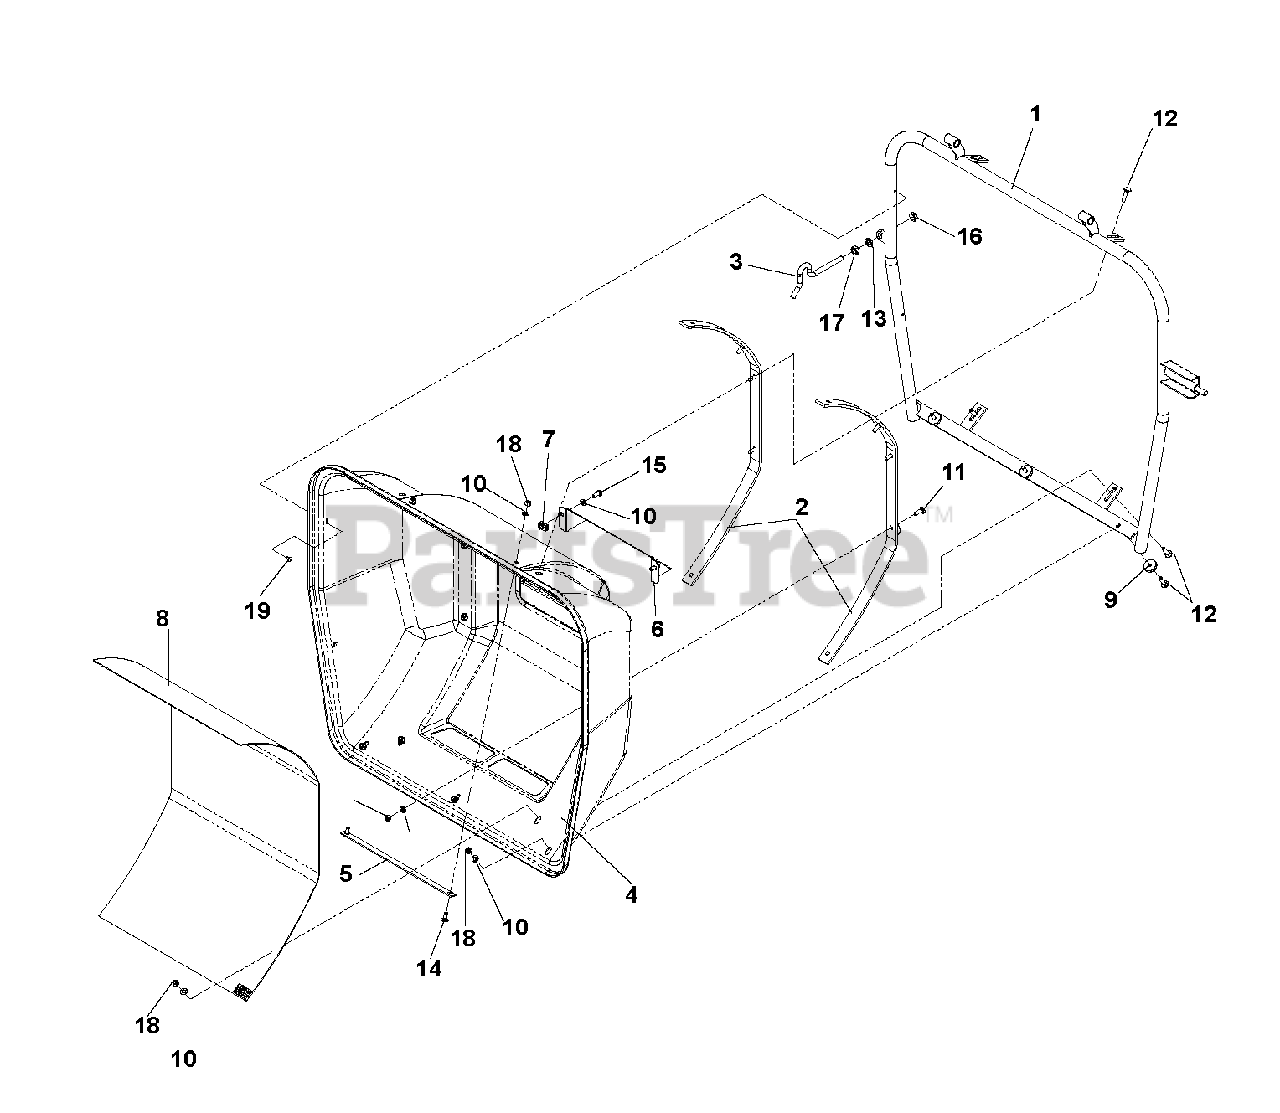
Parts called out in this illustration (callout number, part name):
1	DRIVE PULLEY
3	HOOK LATCH
4	CLAM SHELL (BACK)
6	CLAMSHELL VENT
7	CLIP NUT 5/16-18
8	VENT SCREEN
9	WASHER NYLON
10	FLAT WASHER 5/16 SAE
11	RHSSNB 5/16C X 1.0
12	BOLT, CARRIAGE 5/16X1-1/4
13	WASHER 1/2" SPLIT LOCK
14	BOLT 5/16C X 3/4" CARRIAGE
15	SCREW 5/16C X 1 HEX CAP
16	NUT, 1/2-13 THIN PROF NYL
17	NUT 1/2 HEX JAM
18	NUT 5/16 NYLOC
19	LARGE DOME RIVET
